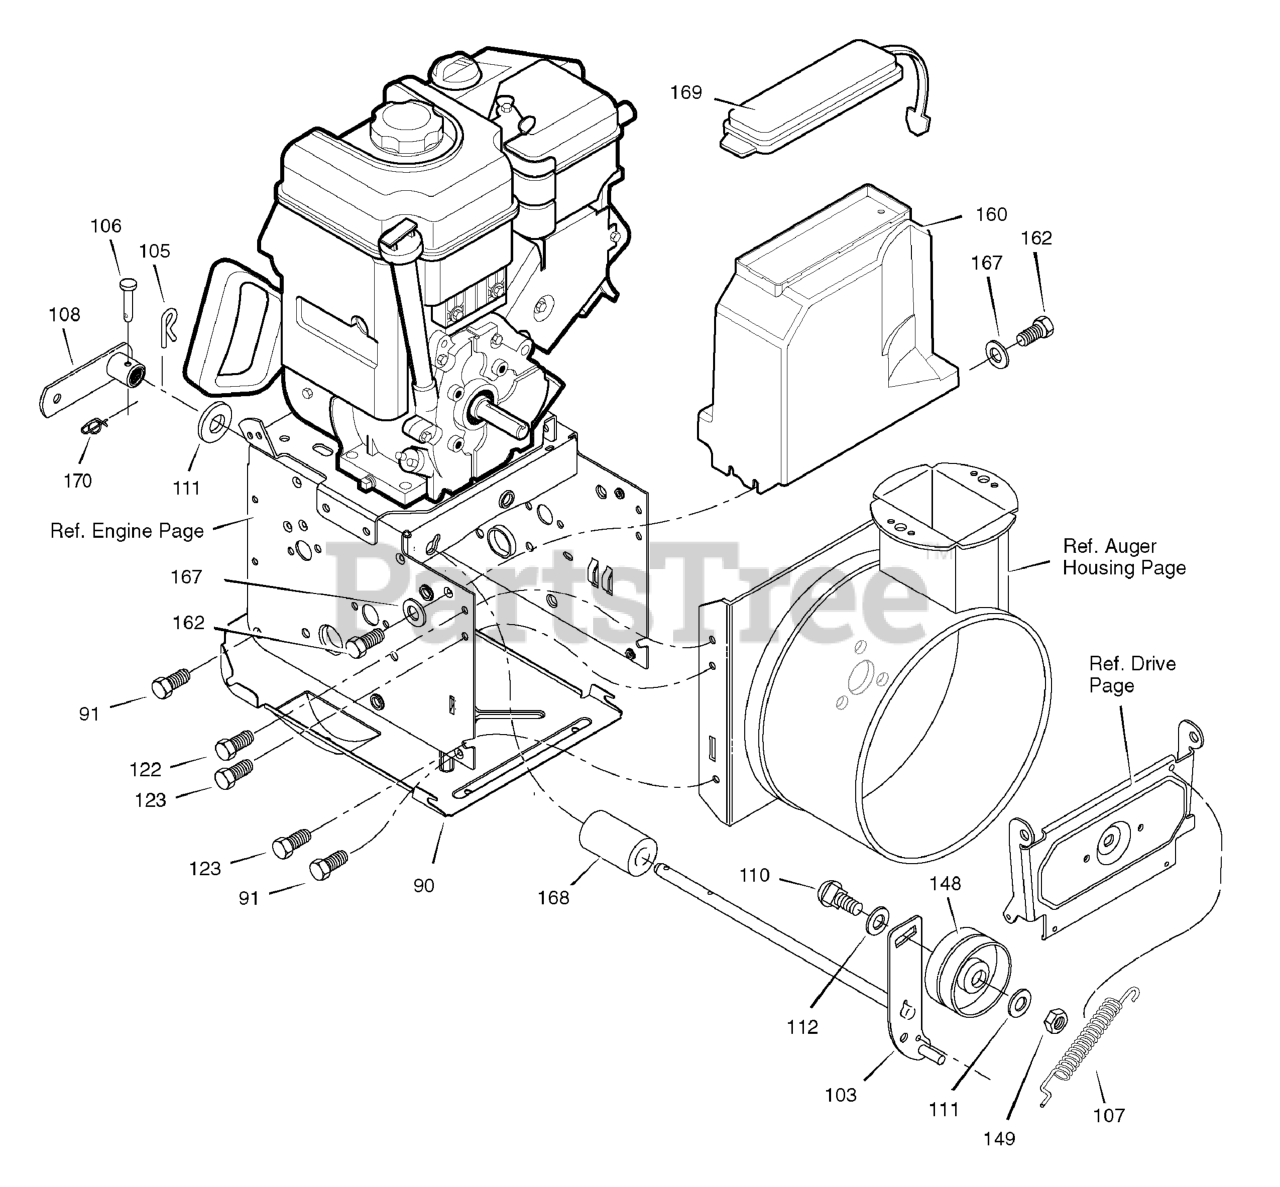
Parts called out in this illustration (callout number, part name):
90	COVER, Bottom
91	SCREW, 1/4 - 20 x 5/8
103	IDLER ASSEMBLY, Auger
105	PIN, Hair
106	PIN, Clevis
107	SPRING, Tension
108	ARM CONTROL
110	BOLT, Carriage, Short Neck, 3/8-16 x 1-1/2
111	WASHER, Flat
122	SCREW, Tap, 5/16 - 18 x 3/4
123	SCREW, Tap, 5/16 - 18 x 1/2
148	PULLEY, Idler
149	NUT, Jam, 3/8 - 16
160	COVER, Belt
162	SCREW, Tap
167	WASHER, Flat
168	SPACER, Auger Bracket
169	LID, Tool Box
170	PIN, Cotter, Self-Locking, 1/4"
